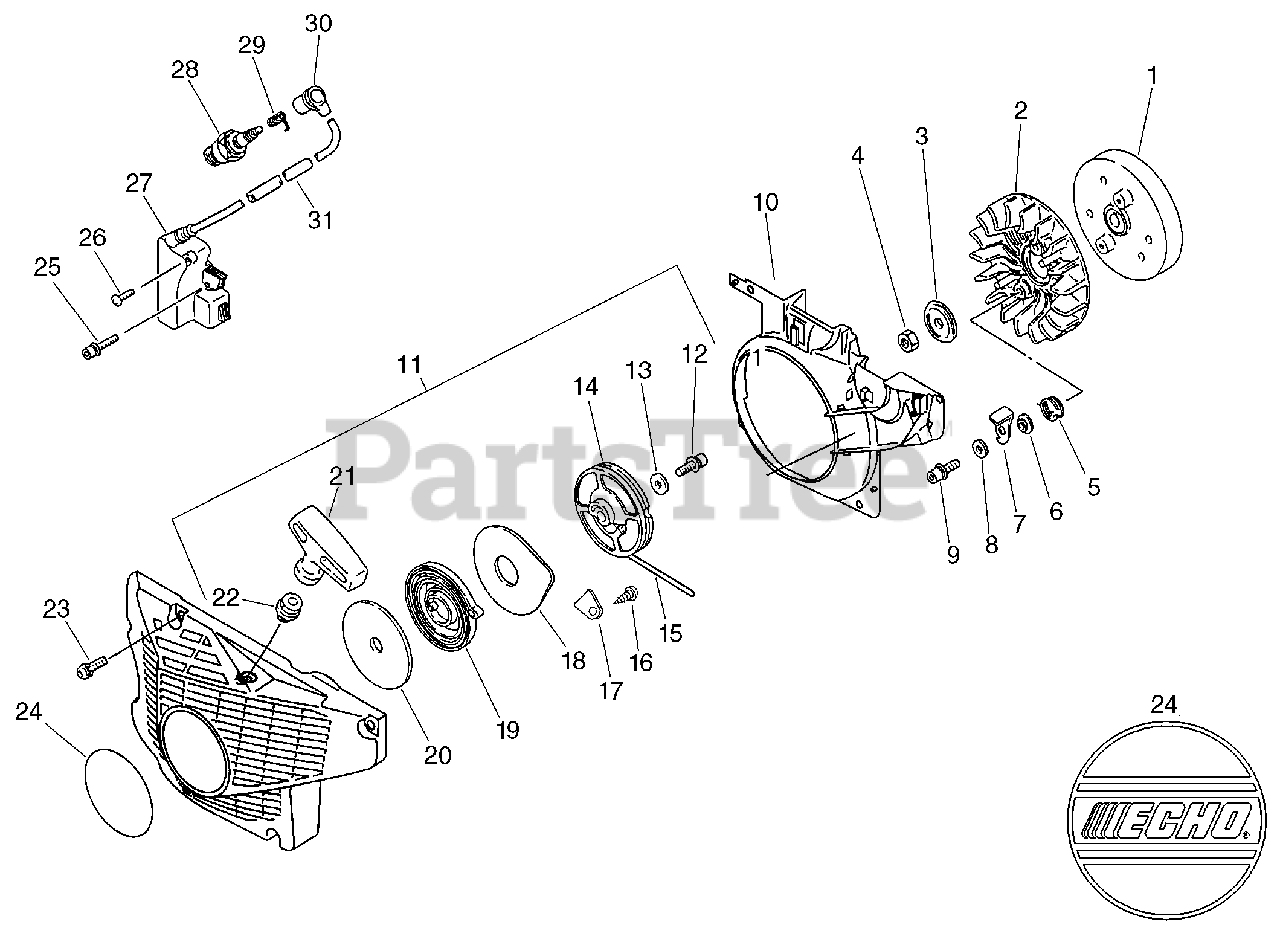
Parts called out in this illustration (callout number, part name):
1	FLYWHEEL
3	WASHER - CUP
5	SPRING, RETURN
7	PAWL, STARTER
8	WASHER - 5
9	SCREW - 5X14
10	COVER, FAN
11	STARTER ASSY
12	SCREW - 5X14
13	WASHER - 5
14	REEL, ROPE
15	ROPE, STARTER - 4X900
16	SCREW - 4X8
17	RETAINER, BRAKE BAND
18	PLATE, STARTER
19	SPRING, REWIND
20	PLATE, STARTER
21	GRIP, STARTER
22	GUIDE, ROPE
23	SCREW - 5X20
24	LABEL - ECHO
25	SCREW - 4X20
26	SCREW - 4X8
27	COIL, IGNITION
28	SPARK PLUG -- BPMR-7A
29	TERMINAL, SPARK PLUG CAP
30	CAP, SPARK PLUG
